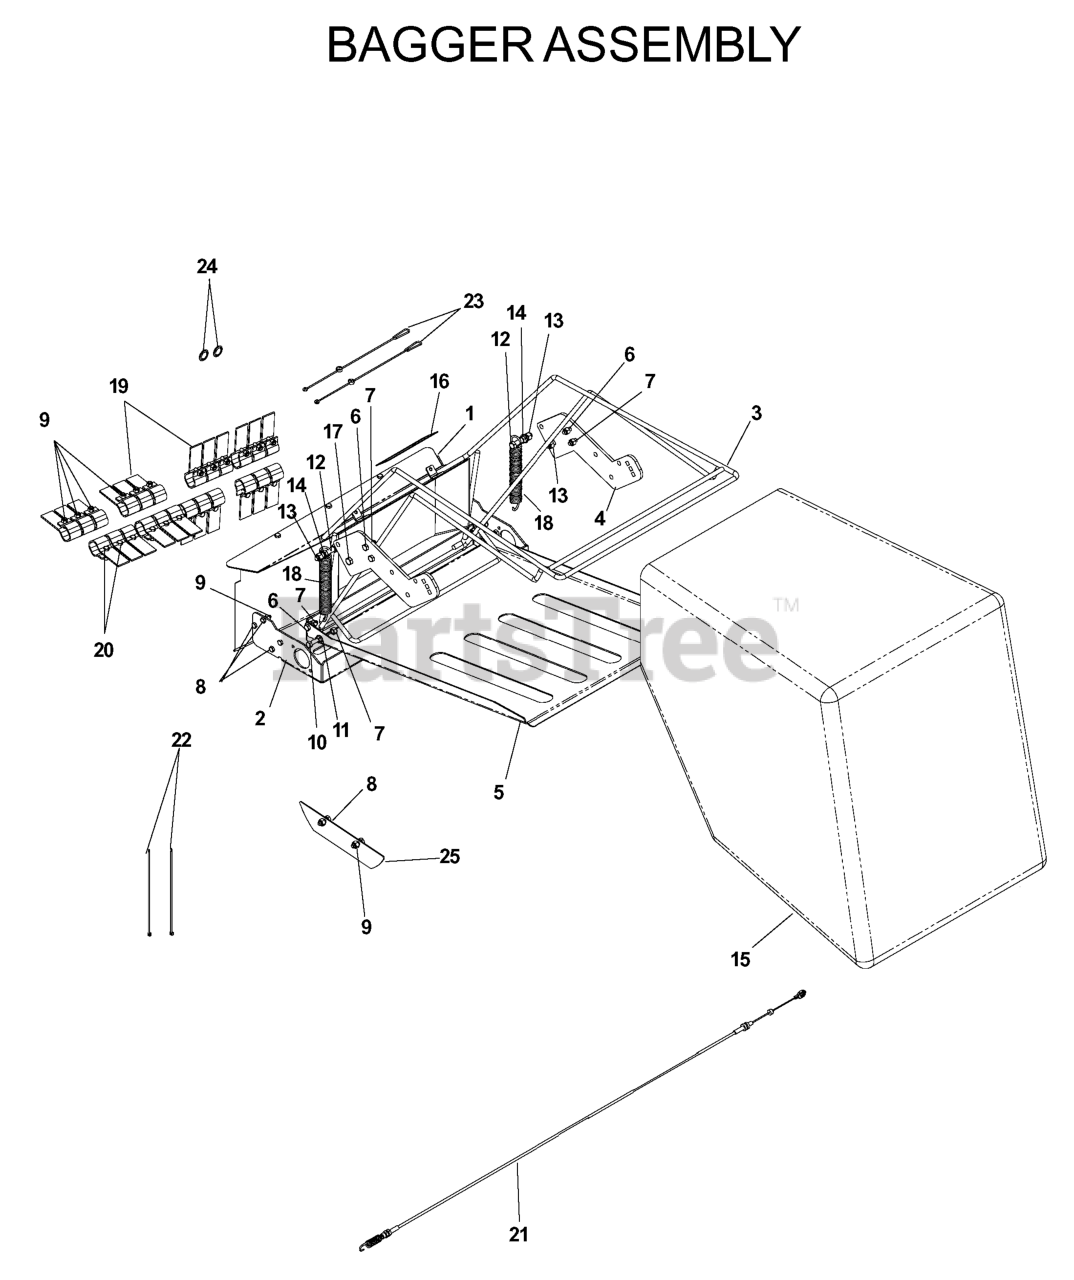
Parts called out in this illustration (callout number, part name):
1	CHUTE
2	BAGGER TRAY
3	BAG FRAME, BLACK
4	EXTENDER GREY
5	SAFETY DOOR ORANGE
6	HCS 5/16C X 1
7	NUT 5/16 NYLOC
8	HCS 1/4C X 3/4 HCS
9	NUT.1/4-20.HEX.NYLOC.ZD
10	HCS 5/16C X 1 3/4
11	NUT 5/16C WHIZ
12	HCS 3/8C X 2
13	NUT 3/8-16 NYLOC
14	NUT 3/8C WHIZ
15	CATCHER BAG
16	DECAL, BAGGING GRAPHIC
17	HCS 3/8-16X1.GRD.5.ZD
18	SPRING BAGGER
19	RUBBER FLAP
20	HCS 1/4C X 1
21	CABLE 46.5" POWER RAKE
22	TIE, PLASTIC
24	R/B 109304 RTNG RG SELF LCK
25	SIDESHIELD
539107244	DECAL, HANDLE PIN
